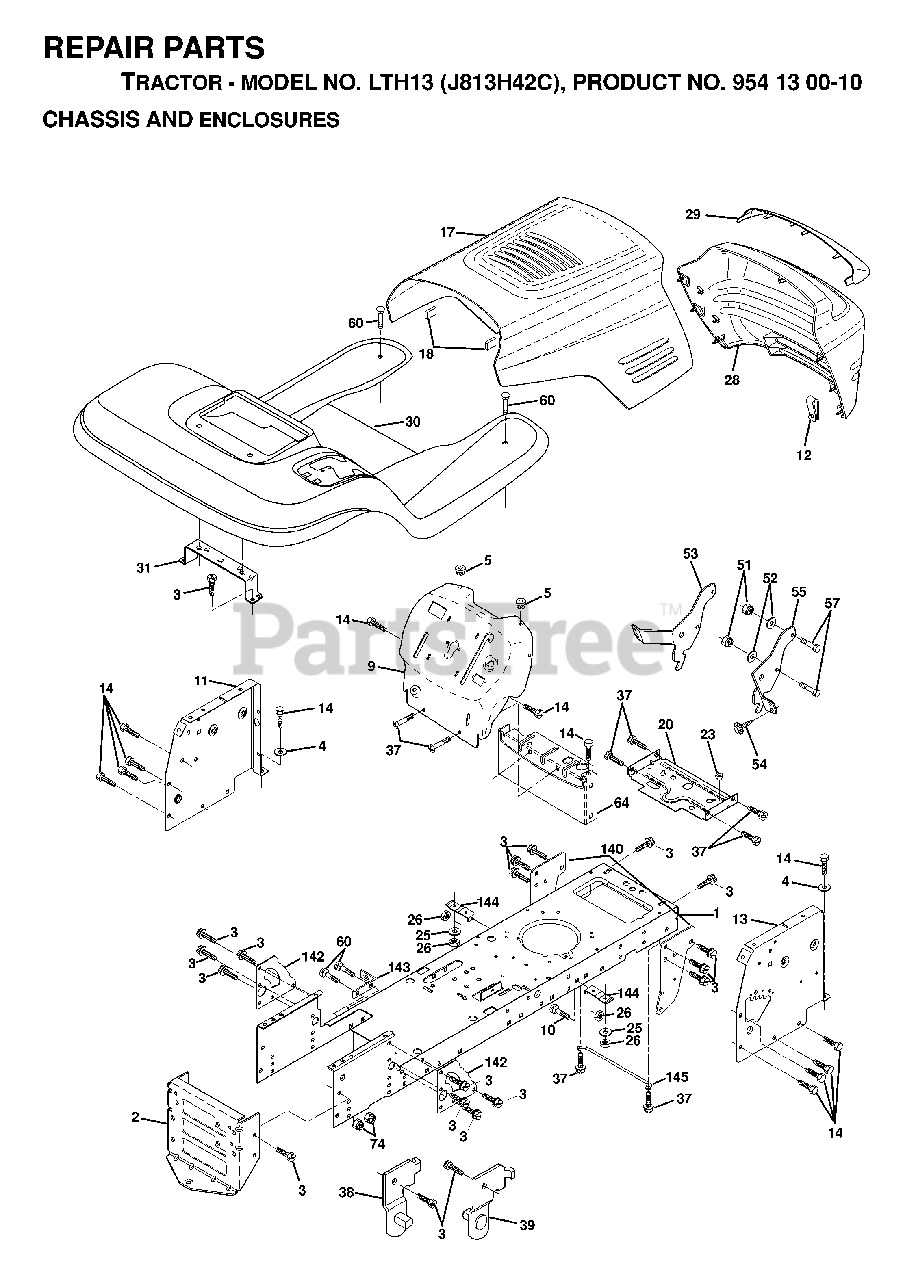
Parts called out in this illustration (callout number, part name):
2	STRETCH DRAWBAR
3	SCREW
5	BUMPER.RUBBER.HOOD
10	BOLT D
11	PANEL DASH LH
13	DASH PANEL
18	BUMPER HOOD T
20	PLATE MTG
23	GROMMET T
25	WASHER
26	NUT
38	BRACKET LH PIVOT
39	BRACKET RH PIVOT
51	LOCKNUT
57	BOLT
64	DASH LOWER
74	LOCKNUT
140	BRACKET SUSPENSION FRONT
142	PLATE REINFORCEMENT
143	BRACKET, SWAY BAR
144	BRACKET FOOTREST
145	ROD PIVOT CHASSIS/HOOD
